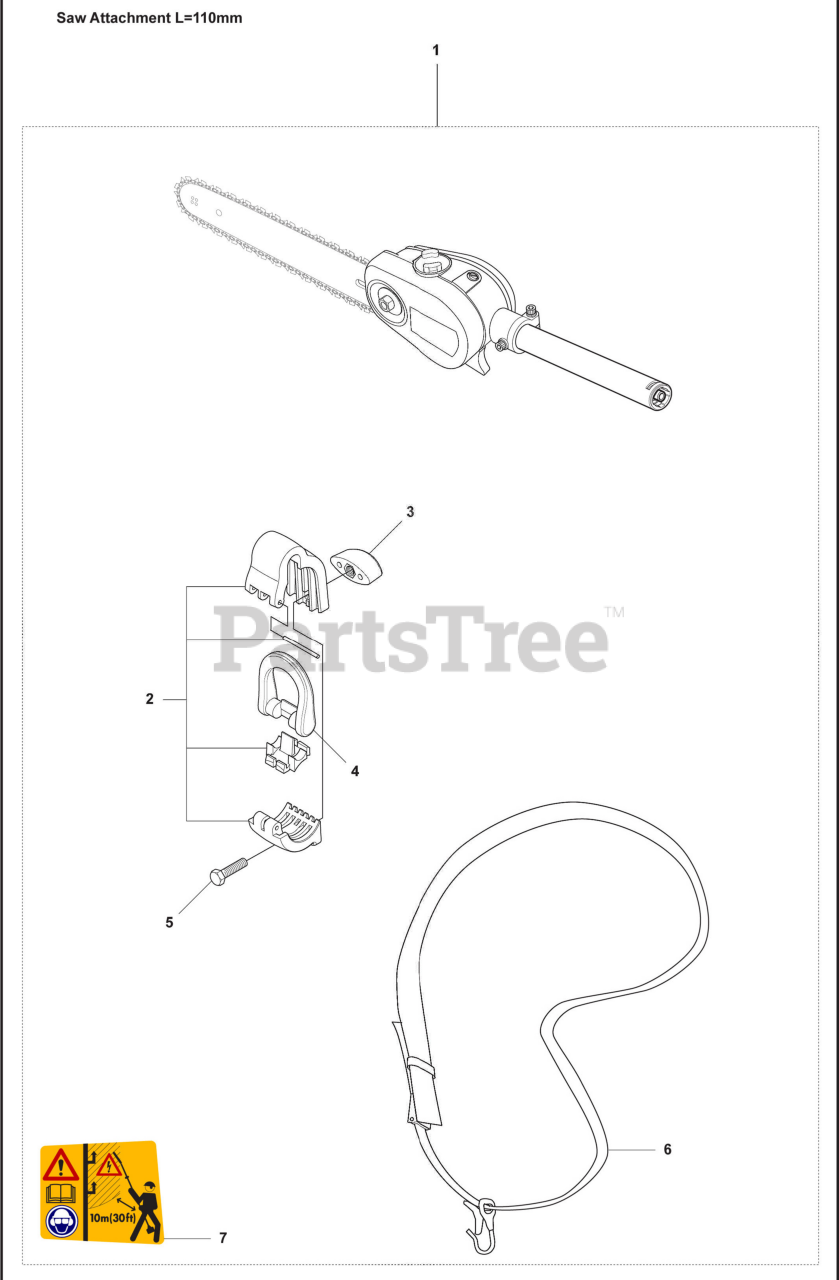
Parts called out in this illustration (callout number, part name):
2	Hanging Bracket
5	Screw, M6S 5 X 20
6	Shoulder Strap with Sign
7	Decal
